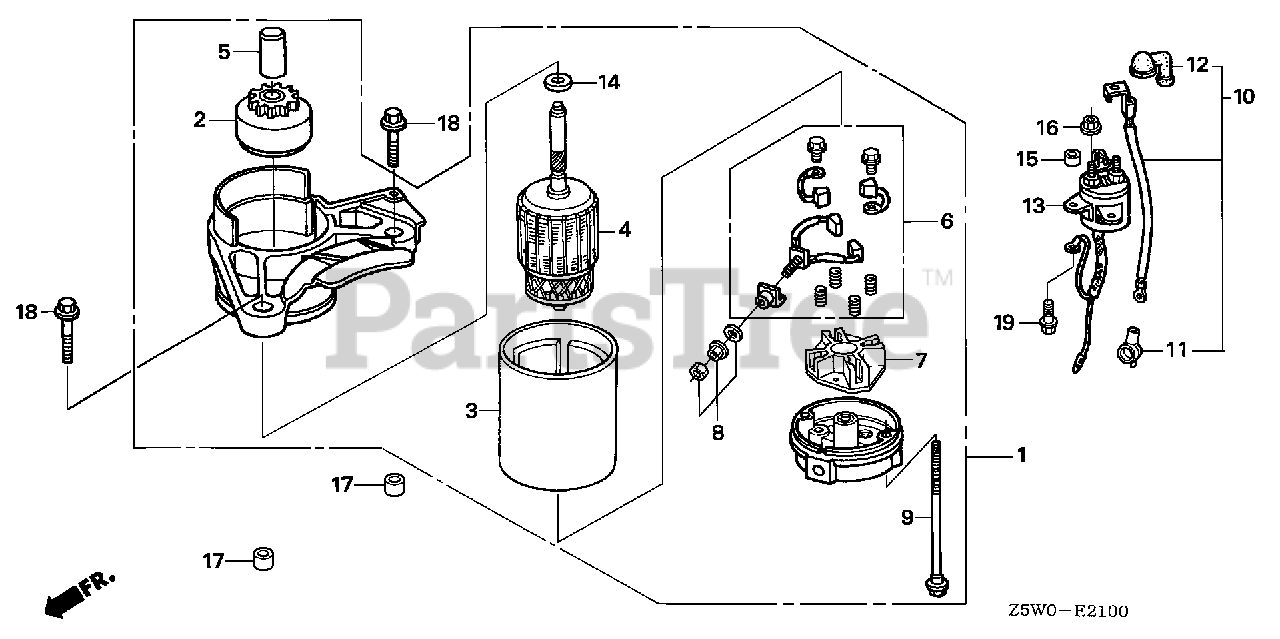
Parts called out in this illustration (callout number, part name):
1	STARTER MOTOR ASSY.
2	DRIVE ASSY.
5	STOPPER SET, PINION
6	BRUSH SET
7	HOLDER, BRUSH
8	NUT SET, TERMINAL
9	BOLT, THROUGH
10	WIRE, MAGNETIC SWITCH
11	COVER, STARTER TERMINAL
12	COVER, MAGNETIC SWITCH TERMINAL
13	SWITCH ASSY., STARTER MAGNETIC
14	WASHER, THRUST
15	COLLAR, DISTANCE
16	NUT-WASHER (6MM)
17	PIN, DOWEL (10X12)
18	BOLT, FLANGE (8X35)
19	BOLT, FLANGE (6X25)
